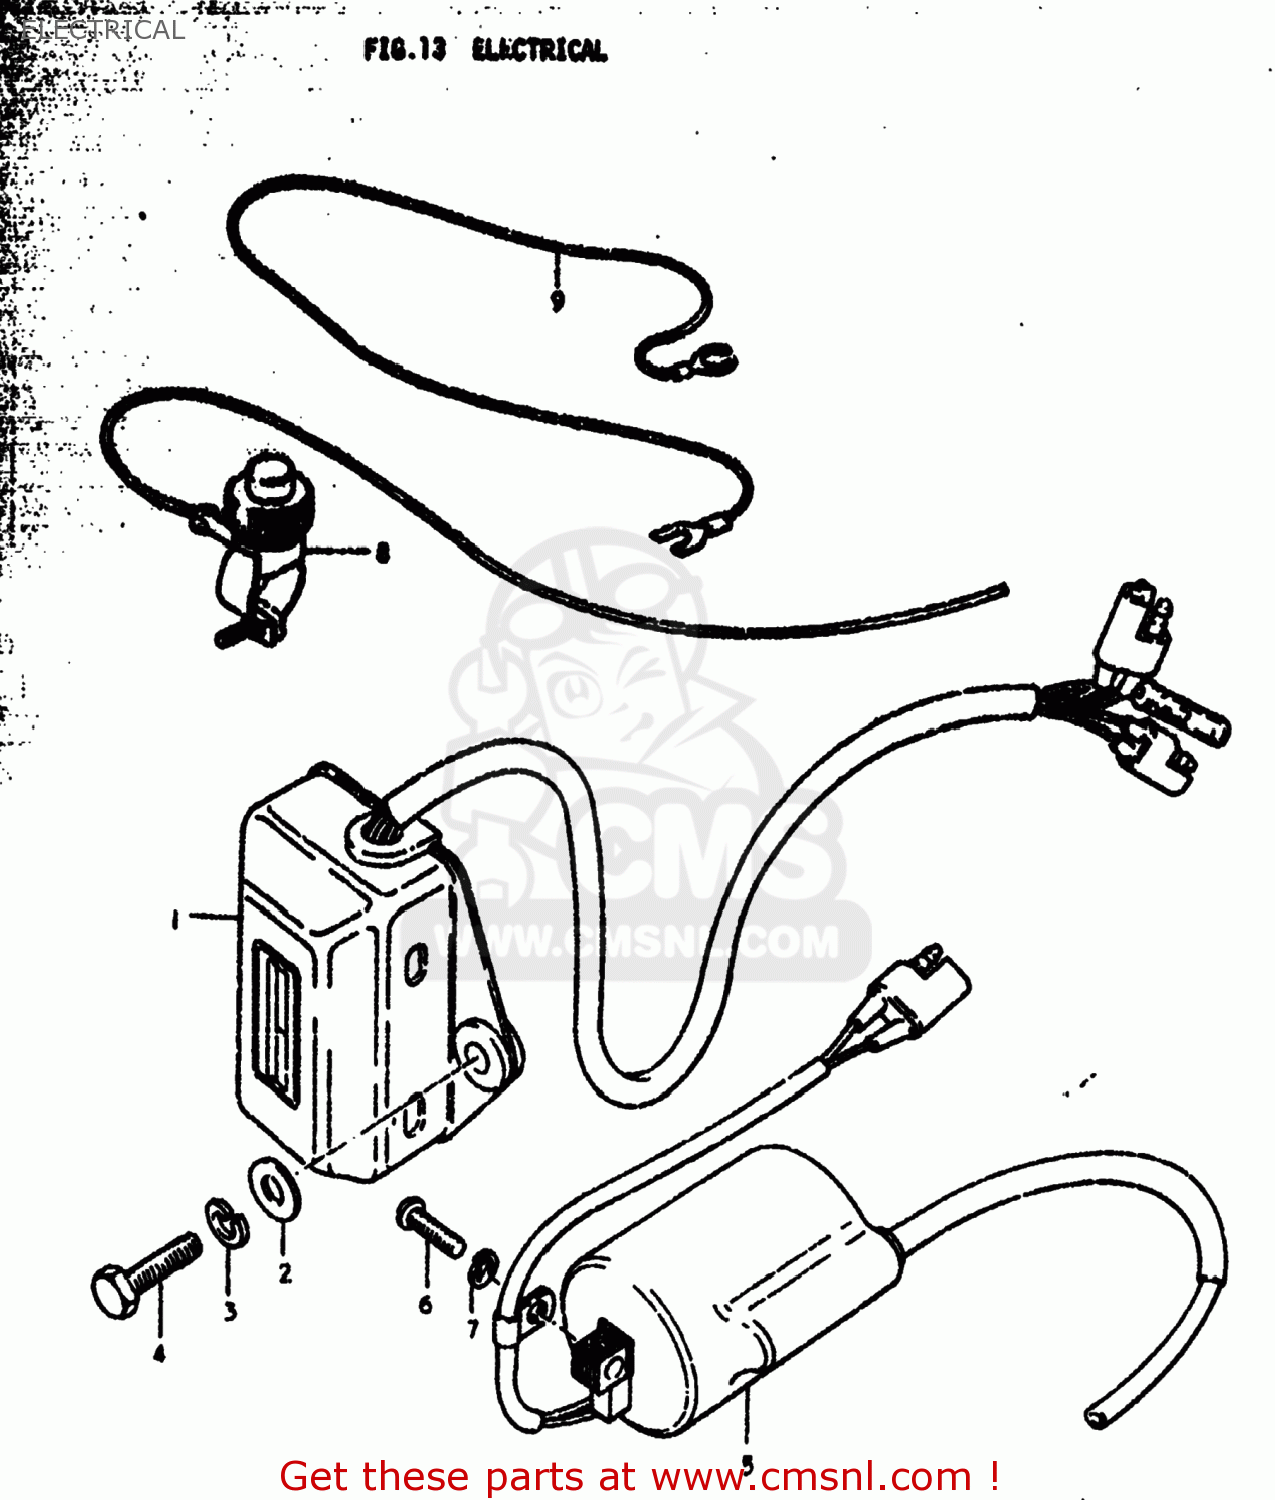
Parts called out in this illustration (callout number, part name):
1	CDI UNIT ASSEMBLY
2	WASHER(6.5X16X1.2)
3	LOCK WASHER
4	BOLT
5	COIL ASSY,IGNITION
6	SCREW 5X20
7	LOCK WASHER
8	SWITCH ASSEMBLY
9	WIRE,ENGINE STOP EARTH
